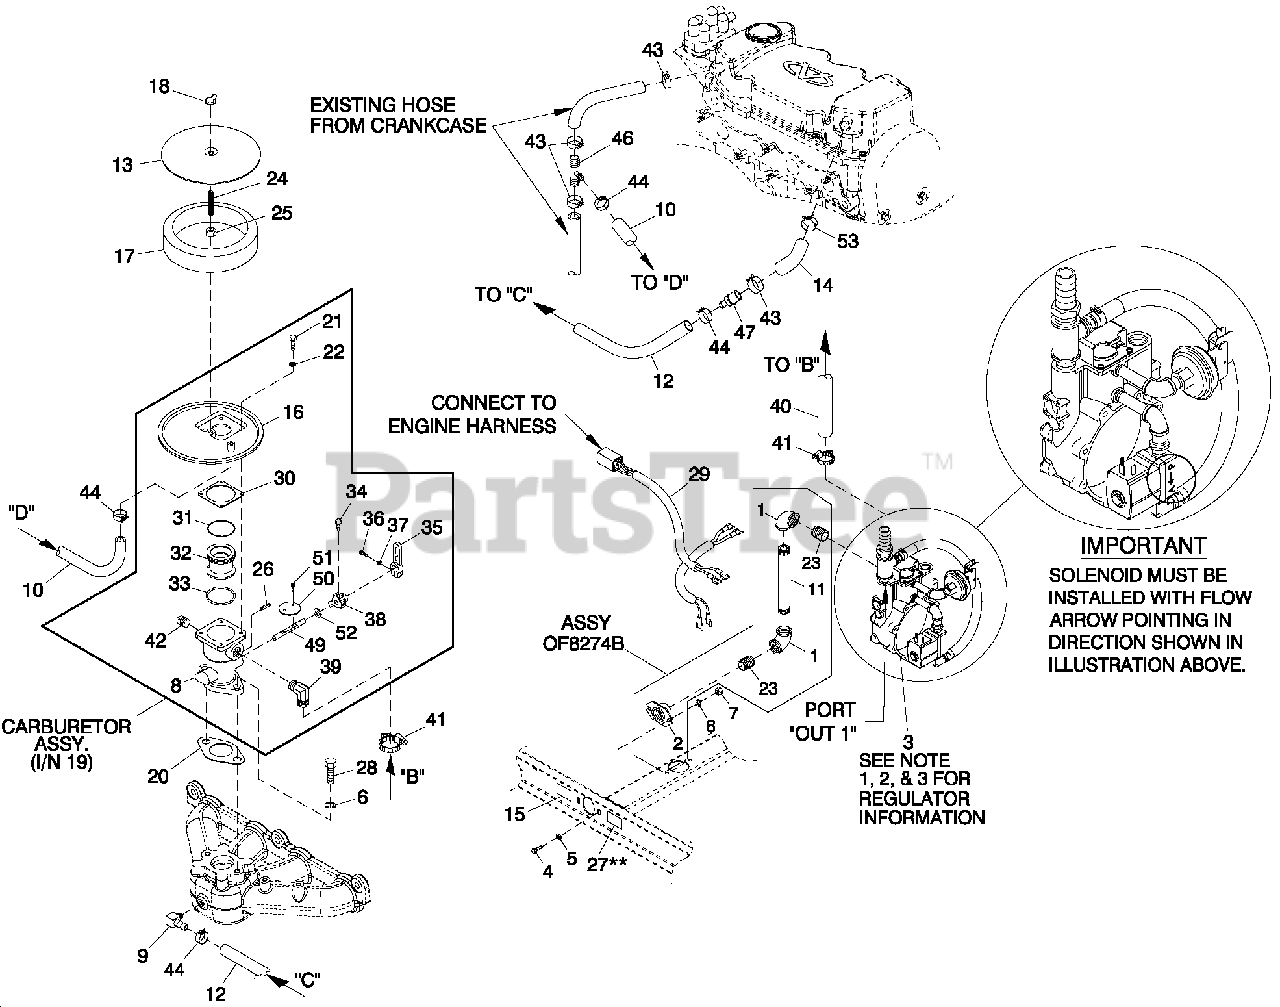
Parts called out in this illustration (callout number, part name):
1	ELBOW 90D 3/4 NPT
2	FLANGE FUEL INLET
3	FUEL REG. REWORK 1.6L 3600 '07 (3600RPM)
4	SCREW HHC M8-1.25 X 20 G8.8
5	WASHER FLAT 5/16 ZINC
6	WASHER LOCK M8-5/16
7	NUT HEX M8-1.25 G8 YEL CHR
8	BODY CARBURETOR ASSEMBLY
9	BARBED EL 90 1/8 NPT X 3/8
10	HOSE 3/8 ID LOW PRES OIL/WATER (16" LG)
11	NIPPLE PIPE 3/4 NPT X 6
12	HOSE 3/8 ID LOW PRES OIL/WATER (12" LG)
13	COVER AIR CLEANER
14	HOSE BREATHER 1.6L
15	DECAL INLET PRESSURE
16	ADAPTER CARB. TO A IR CLNR
17	FILTER ELEMENT
18	NUT WING 1/4-20 NYLK
19	ASSY CARBURETOR 1.6L 3600RPM
20	CARBURETOR GASKET
21	SCREW PPHM M5-0.8 X 12 ZNC
22	WASHER LOCK M5
23	NIPPLE CLOSE 3/4 X 1.375
24	STUD TH 1/4-20 X 3 G2 ZNC FULL
25	NUT HEX 1/4-20 STEEL
26	PIN SPRING 3/16 X 5/8
27	DECAL FUEL INLET NG
28	SCREW HHC 5/16-18 X 1 G5
29	HARNESS FUEL JUMPER SINGLE REG
30	GASKET AIR CLEANER ADAPTER
31	O-RING 2-028 1.38 X 1.50 X .06
32	VENTURI 20MM (3600RPM)
33	O-RING 29.82 X 2.62
34	SCREW THROTTLE PIN STOP
35	THROTTLE ARM REWORK
36	SCREW HHM #10-32 X 5/8
37	WASHER LOCK #10
38	LEVER THROTTLE STOP
39	BARBED EL 90 3/8 NPT X 5/8
40	HOSE 5/8 ID LPG & NG (12" LG)
41	CLAMP HOSE #10 .56 - 1.06
42	PLUG STD PIPE 1/4 STEEL SQ HD
43	CLAMP HOSE BAND 1.0"
44	CLAMP HOSE BAND .63
46	HOSE BARB REDUCR TEE 3/4M-3/8M
47	PCV VALVE 2.5L FORD
49	SHAFT THROTTLE 1.5L
50	THROTTLE VALVE PLATE 27MM
51	SCREW RHMS 6-32 X 1/4 ZINC
52	SEAL SHAFT COVER
53	CLAMP HOSE BAND .88"
